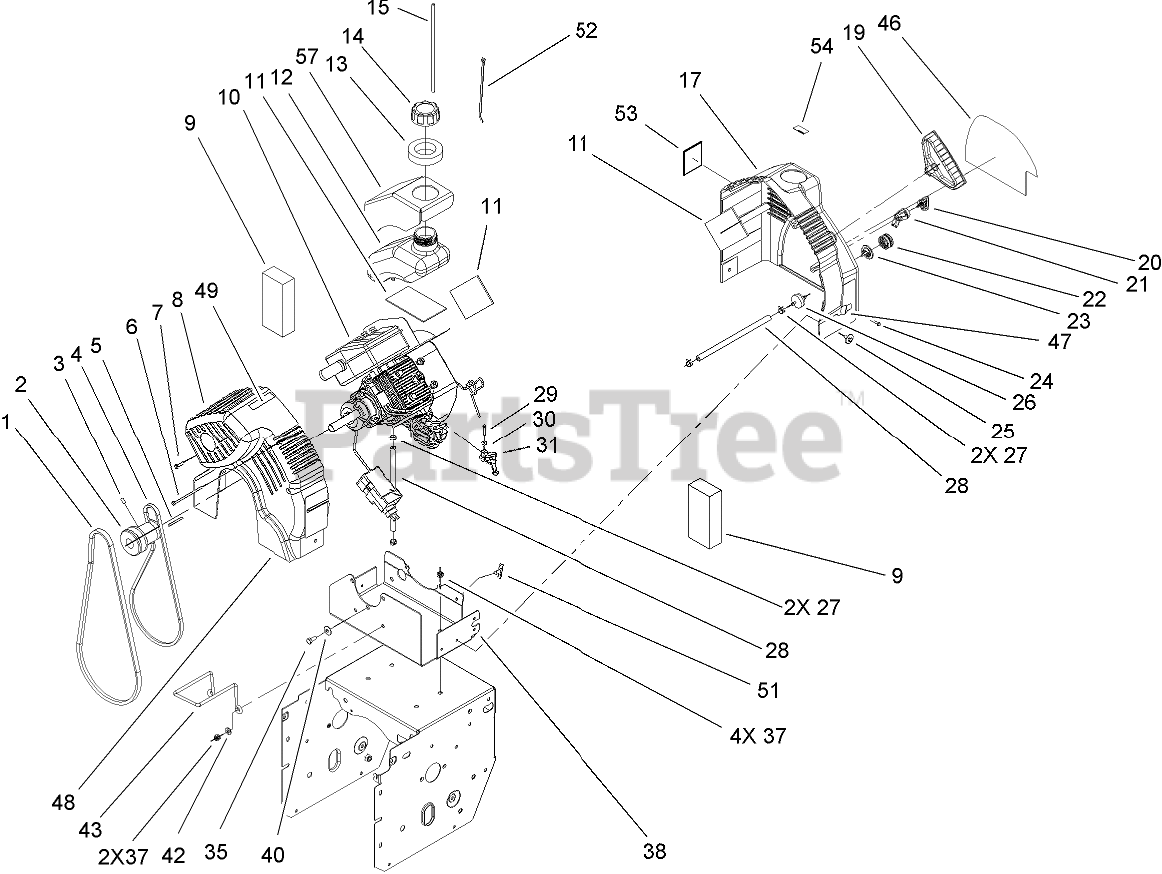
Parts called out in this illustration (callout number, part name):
1	BELT-V
2	PULLEY-ENGINE
3	SCREW-SET, HSH
4	V BELT-TRACTION
5	KEY-SQUARE
7	SCREW-HWH
8	COVER-FRONT, STYLING
11	PAD-FOAM
12	TANK-FUEL
13	SEAL-FOAM
14	GAS CAP ASM
15	HOSE-PRIMER
17	COVER ASM
19	HANDLE-ROPE START
20	KEY-IGNITION
21	SWITCH
22	BULB-PRIMER
23	BODY-PRIMER
24	SCREW-PLASTITE
25	SCREW-WASHER HEAD
26	FILTER-FUEL
27	CLAMP-HOSE
28	LINE-FUEL
29	SCREW-PPH, PLASTITE
30	WASHER-FLAT
31	LEVER-CHOKE
35	SCREW-HH
37	NUT-LOCK, NI
38	PLATE-MOUNTING, ENGINE
40	WASHER-BELLEVILLE
42	WASHER-PLAIN
43	GUIDE-BELT
46	DECAL-PANEL
47	DECAL-STARTER, ELECTRIC
48	DECAL-CHOKE
49	DECAL-WARNING
51	CLIP-HARNESS
52	TIE-CABLE
53	DECAL
54	DECAL-FUEL, 2 CYCLE
57	FOAM-TANK, FUEL
